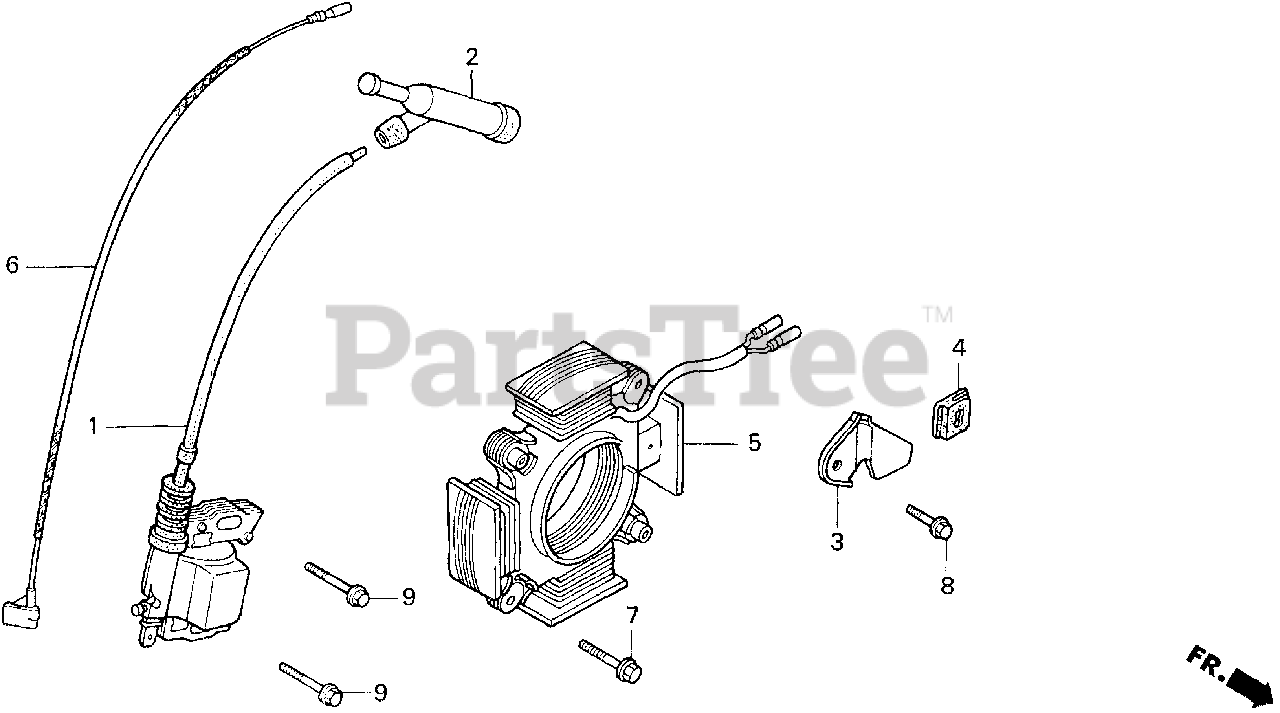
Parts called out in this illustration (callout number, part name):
1	COIL ASSY., IGNITION
2	CAP ASSY., NOISE SUPPRESSOR
6	WIRE, STOP SWITCH (370MM)
9	BOLT, FLANGE (6X25)
